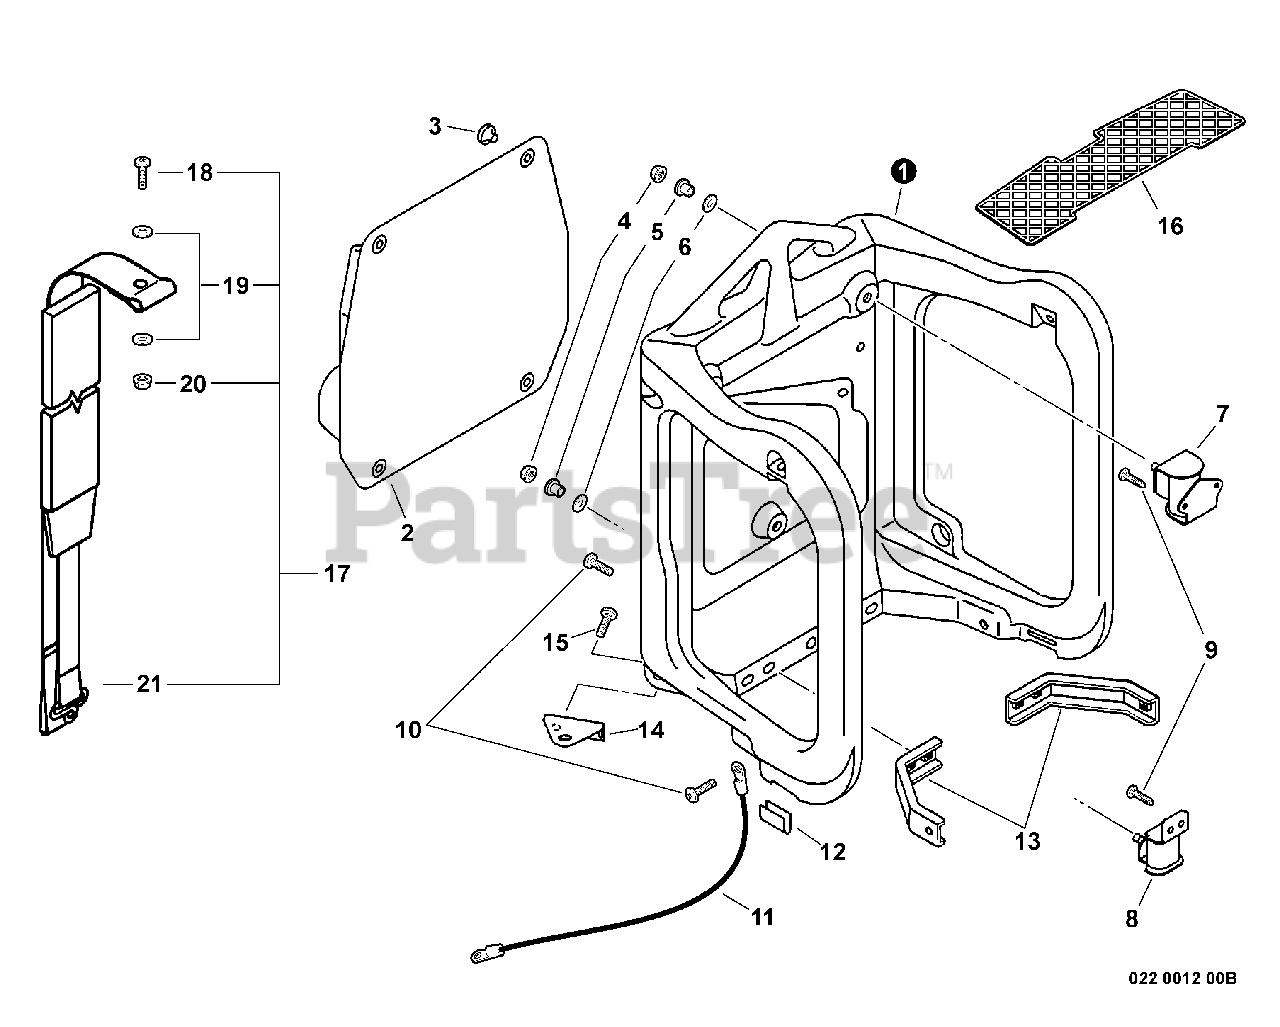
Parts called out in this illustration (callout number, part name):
1	FRAME, BACKPACK
2	CUSHION, BACKPACK
4	NUT, FLANGE M5
8	CUSHION
9	SCREW 5×16
10	SCREW 5×14
11	LEAD - GROUND
12	BUMPER
13	CONNECTOR, FRAME
14	BRACKET, HANGER
15	SCREW 5×20
16	GUARD, DEBRIS
17	BACKPACK STRAP ASSY
18	SCREW 5×14
19	WASHER 5.5×18×1
20	NUT, FLANGE M5
21	RING, HARNESS
